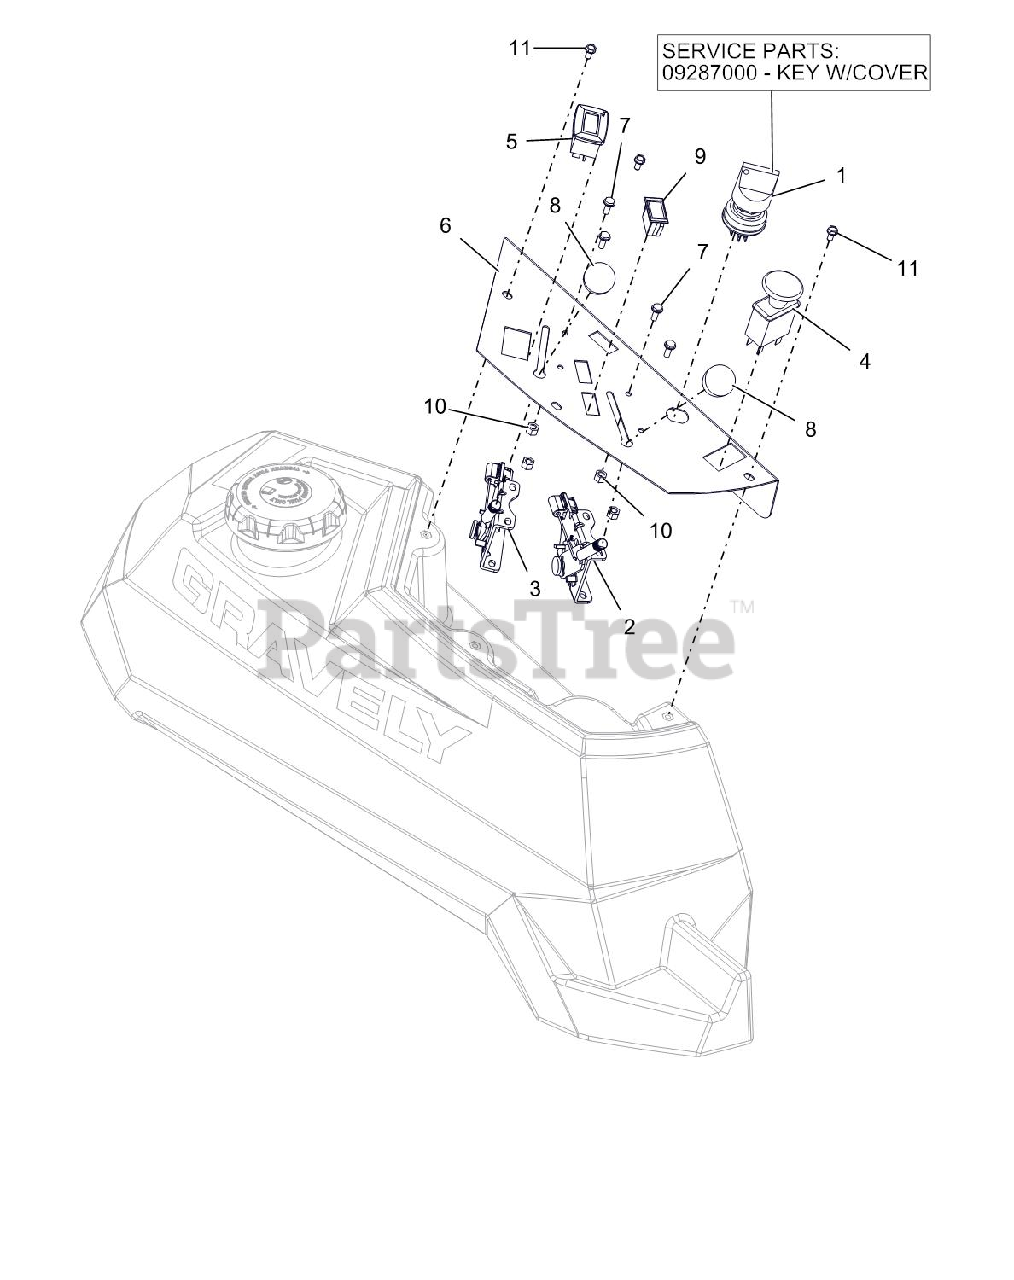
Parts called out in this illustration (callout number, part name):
1	KEY, W/ SHIELD
1	SWITCH, IGNITION
2	CABLE, PRO-CONTROL 28.50
3	CABLE, PRO-CONTROL 31.50"
4	SWITCH, CLUTCH
5	METER, HOUR W/MAINTENANCE
6	PT CONTROL PANEL - RED
7	@SCR-MCH 10-24X.50 HWH YWZC
8	KNOB-CONTROL-BLACK .38-16X.50
9	SWITCH,BLANK
10	@NUT-LK-NYL 10-24 W/INSRT YWZC
11	SCR-MCH 10-24X.38 HWHSTAINLESS
